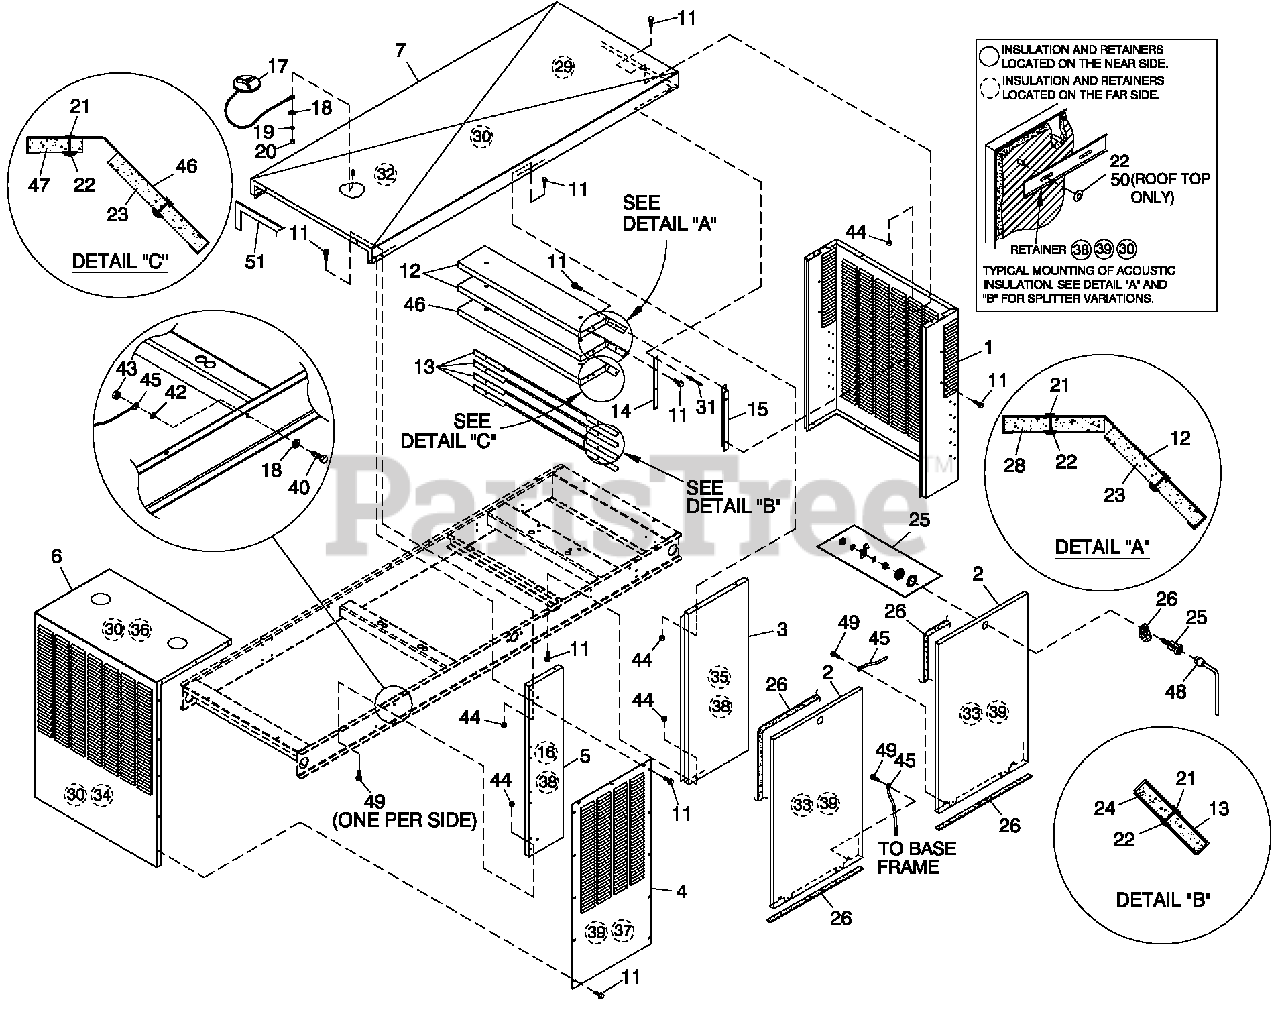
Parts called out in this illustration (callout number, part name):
1	REAR WRAP C5
2	DOOR C5
3	CENTER SUPPORT C5
4	DISCHARGE DUCT LH & RH SIDE C5
5	FRONT CORNERS C5
6	DUCT CENTER DISCHARGE
7	ROOF C5 ALU M
11	SCREW THF M6-1 X 16 N WA Z/JS
12	SPLITTER
13	SPLITTER SHORT
14	STRINGER SPLITTER C3
15	SUPPORT SPLITTER C5 130KW
16	INSULATION CORNER POST
17	ASSY ACCESS COVER
18	WASHER FLAT 1/4- M6ZINC
19	WASHER LOCK M6-1/4
20	NUT HEX 1/4-20 STEEL
21	INSULATION RETAIN MENT HANGER
22	WASHER SELF LOCKING DO ME #4-40
23	INSULATION SPLITTER
24	INSULATION SHORT LOUVER
25	VISE-ACTION LATCH SLOTTED CIR
26	GASKET EXTRUDED TRI M (566" LG)
27	TAB PULL
28	INSULATION SPLITTERS ML
29	INSULATION ROOFTOP REAR
30	RETAINER INSULATION (740)
31	RIVET POP .1875 X .450 SS
32	INSULATION ROOFTOP
33	INSULATION DOOR
34	INSULATION DISCHARGE DUCT
35	INSULATION CENTER SUPPORT
36	INSULATION DISCHARGE DUCT TOP
37	INSULATION INNER DUCT SIDE
38	RETAINER INSULATION (820)
39	RETAINER INSULATION (450)
40	SCREW HHC M6-1.0X20G8.8
42	WASHER SHAKEPROOF INT 1/4
43	NUT H E XM 6X 1 .0G 8Y EL CHR
44	NUT HEX LOCK M6-1.0 SS NY INS
45	ASSY WIRE 14 AWG 34.8" GRN/YEL
46	SPLITTER C5
47	INSULATION SPLITTER SHRTMPS
48	KEY VISE-ACTION LATCH SLOT CIR
49	SCREW TH-FRM M6 W/CAP SHKPRF W
50	WASHER SELF LOCKING DO ME #8-32
51	STRIP SEALANT 1/8 X 1 (44.52+LG)
